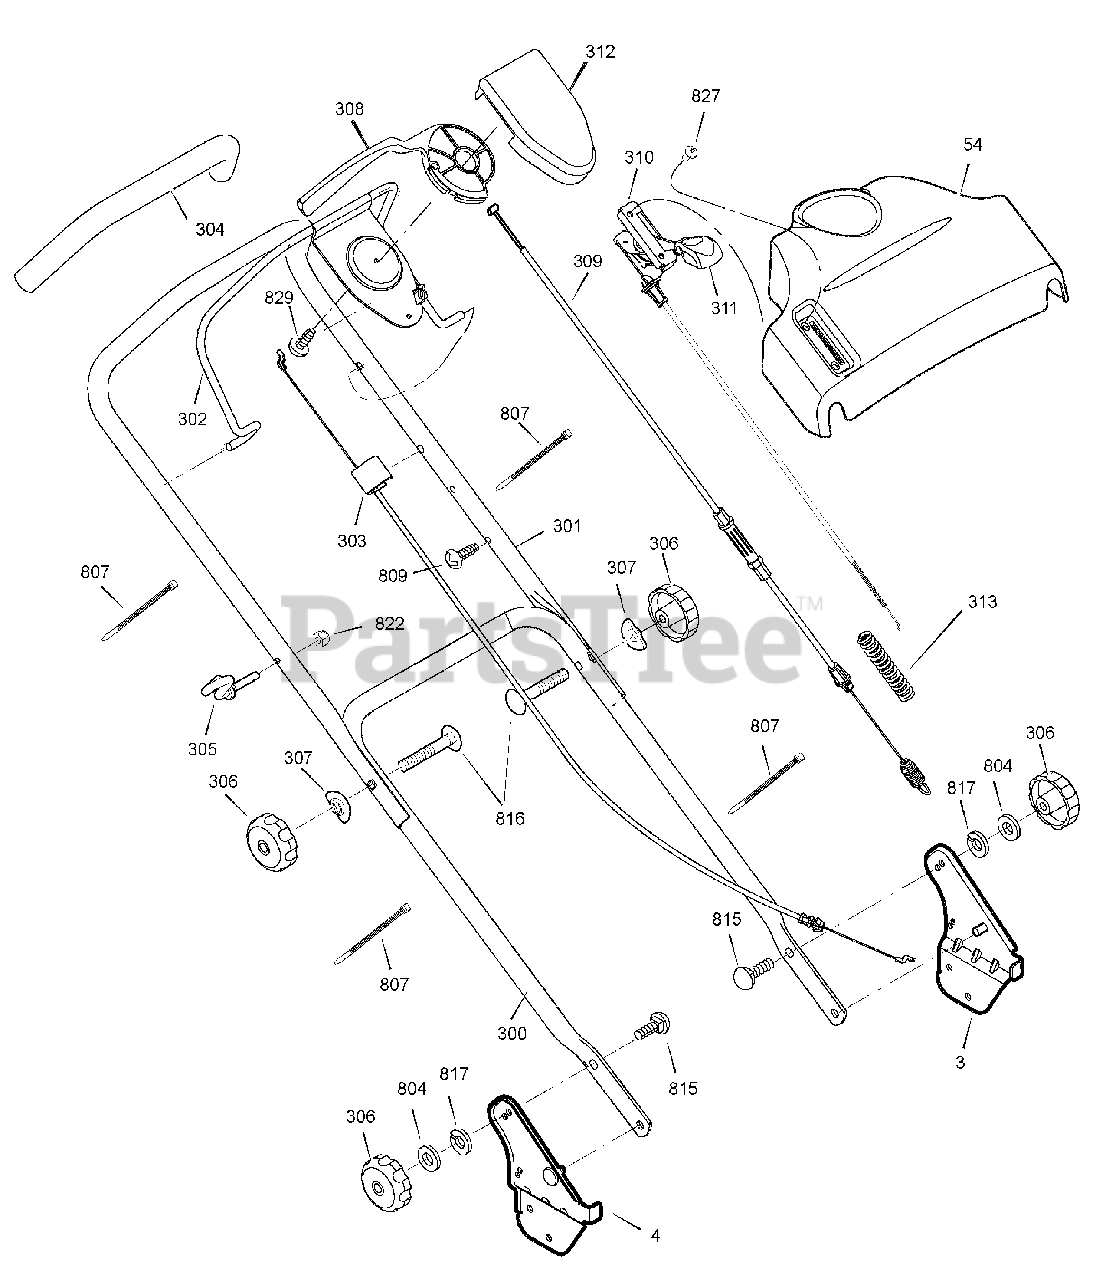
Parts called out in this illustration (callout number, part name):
3	BRACKET ASSEMBLY, Left Handle
4	BRACKET ASSEMBLY, Right Handle
54	CONTROL PANEL
300	HANDLE, Lower
301	HANDLE, Upper
302	LEVER, Engine Stop
303	CABLE, Engine Stop
304	TUBING, Foam
305	GUIDE, Rope
306	KNOB, Adjuster
307	WASHER, Formed
308	LEVER, Drive
309	CABLE ASSEMBLY, Drive
310	THROTTLE CONTROL
311	KNOB, Throttle Control
312	COVER, SP Control
313	SPRING, Compression
804	WASHER, 5/8
807	CABLE TIE
809	SCREW, Self Tap, #10-16 x 1/2
815	BOLT, Carriage, 5/16-18 x 1-1/8
816	BOLT, Carriage, 5/16-18 x 2
817	Washer, Lock
822	NUT, Hex, 1/4-20
827	SCREW, 1/4-20 x 7/8
829	SCREW, 1/4-20 x 7/8
